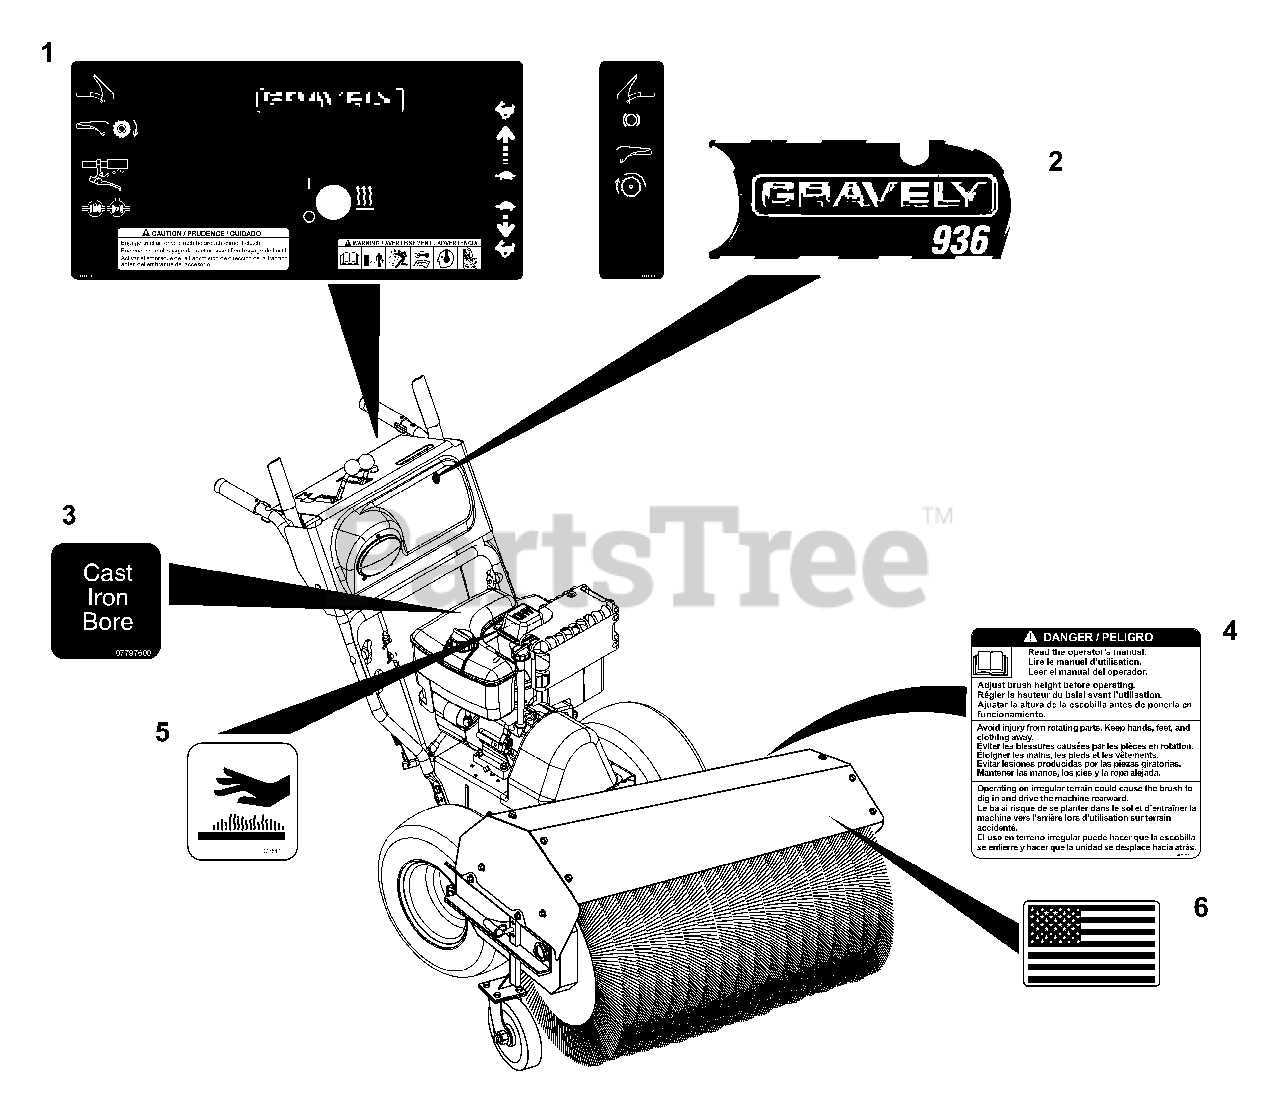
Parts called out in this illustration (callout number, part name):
1	Decal, Control-Gravely PB
2	Decal, Front Dash-Gravely Brush
3	Decal, Cast Iron Bore
4	Decal, Danger
5	Decal, Hot Surface
6	Decal, American Flag
